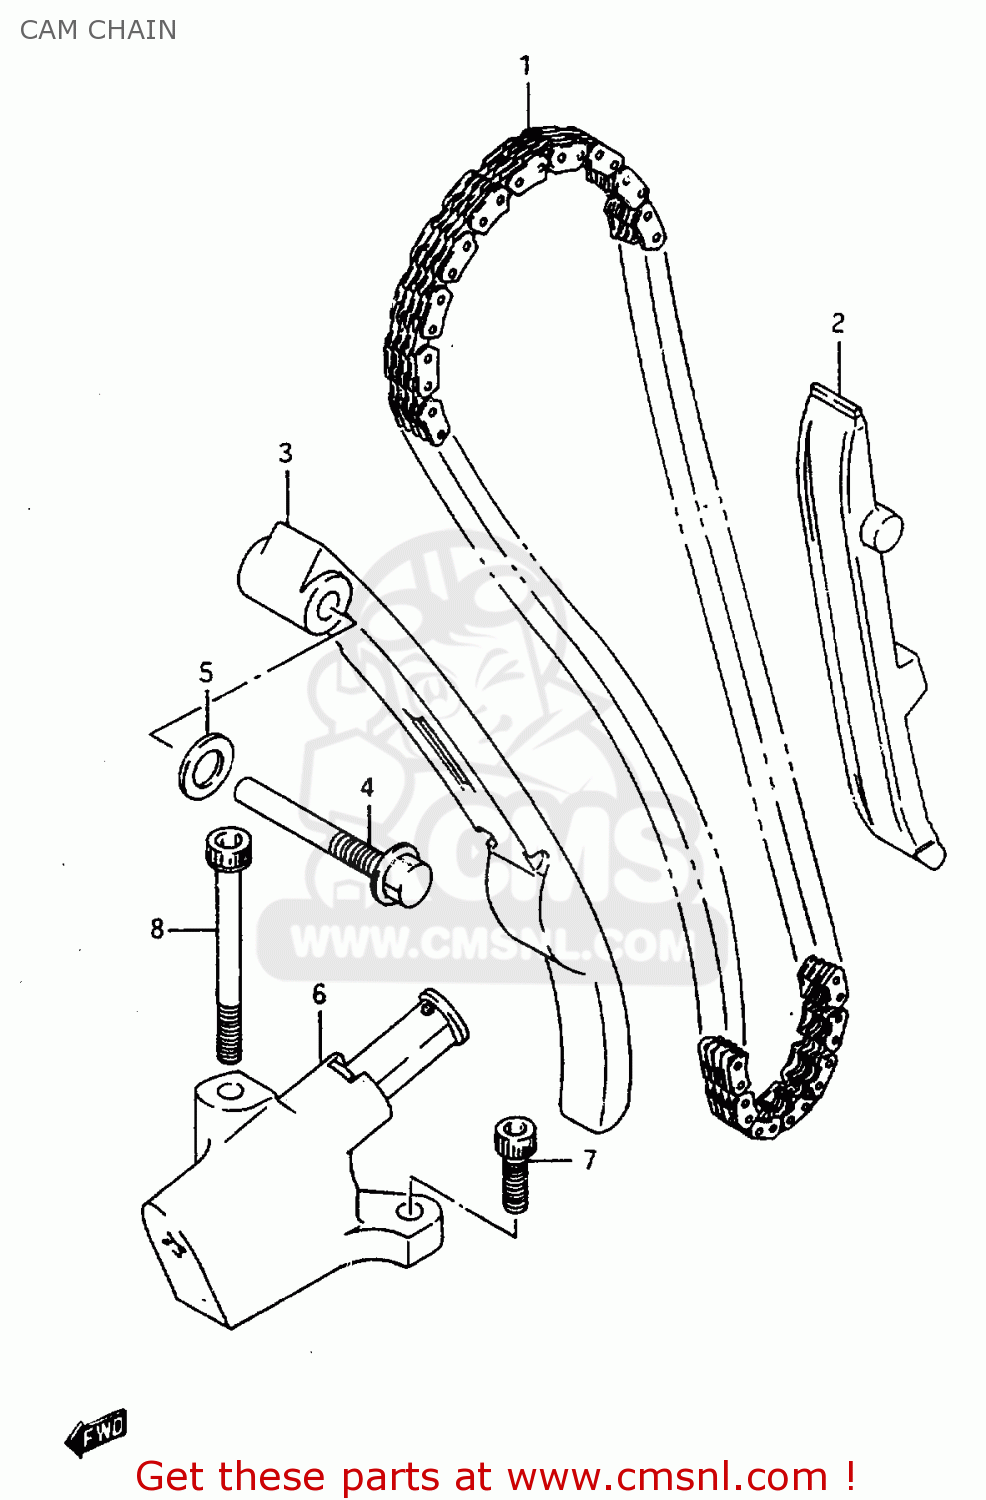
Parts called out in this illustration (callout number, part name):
1	CHAIN,CAMSHAFT DRIVE
2	GUIDE,CAM CHAIN
3	TENSIONER,CAM CHAIN
4	BOLT,CAM CHAIN TENSIONER
5	GASKET 8.2X14X1 (NAS)
6	ADJUSTER ASSY,TENSIONER
7	BOLT,CRKCASE,R
8	BOLT
